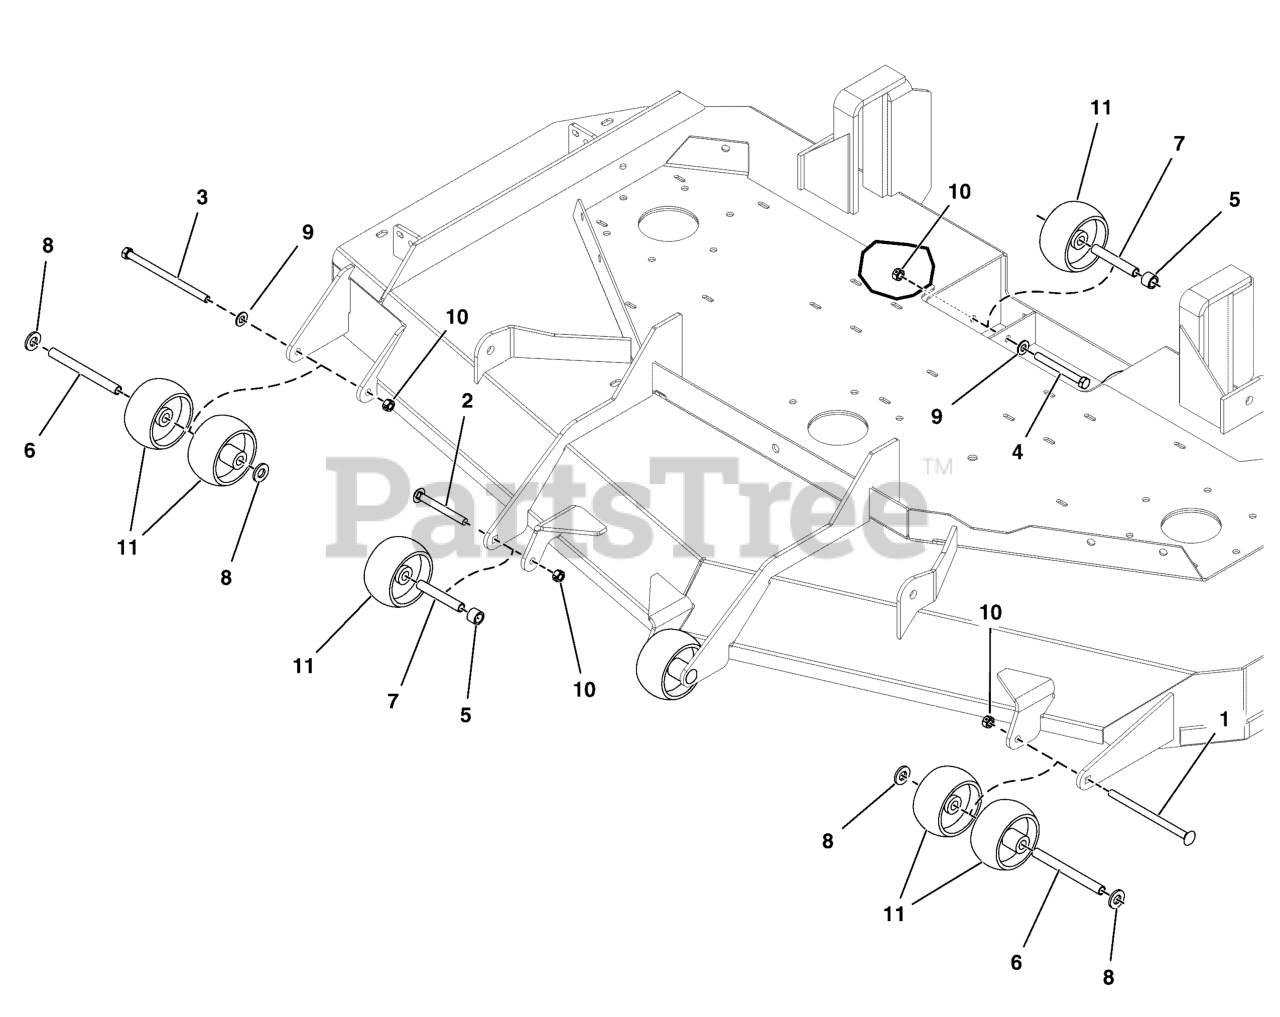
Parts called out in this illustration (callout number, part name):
1	BOLT, 3/8-16 X 6, CARRIAGE, GD5, CZ
2	BOLT, 3/8-16 X 3-1/2, CARRIAGE, GD5, CZ
3	BOLT, 3/8-16 X 6" GD5 CZ
4	BOLT, 3/8-16 X 3-1/2" GD5 CZ
5	SPACER, .51 X .75 X .56, PM, CZ
6	SPACER, .38 X .50 X 5.06, CZ
7	SPACER, .38 X .50 X 2.50, CZ
8	WASHER, 1/2 GD9 CZ
9	WASHER, 3/8 SAE
10	NUT, 3/8-16 HEX SIDE LOCK
11	WHEEL- 2.00 WIDE 3.88 DIA 0.531ID POLY
